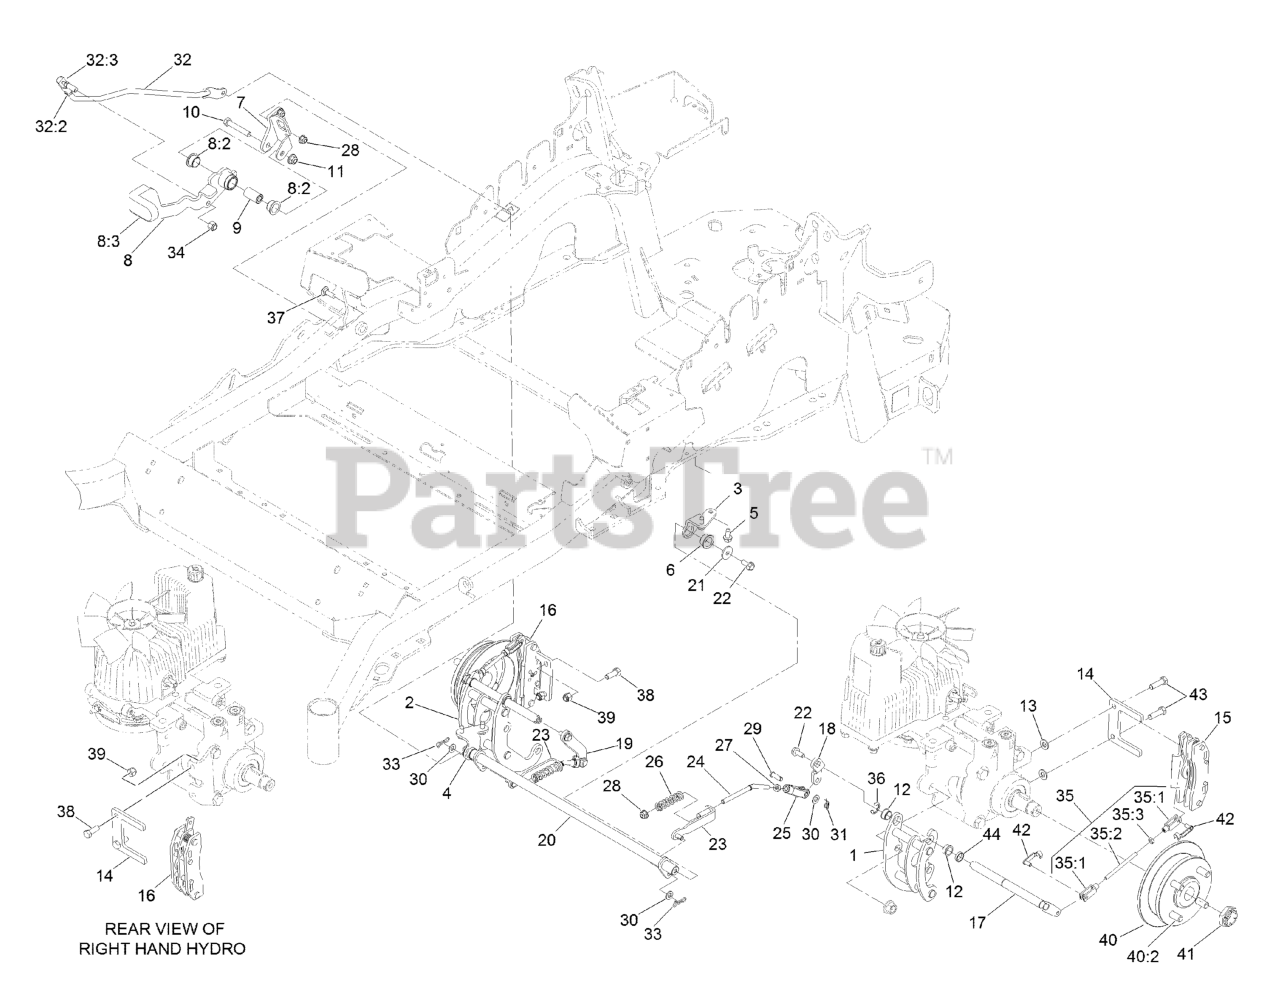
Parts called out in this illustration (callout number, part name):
1	BRACKET-MOUNT
2	BRAKE LEVER ASM W/ GRIP
2:2	BUSHING-FLANGE
2:3	GRIP-LEVER
3	BOLT-CARR
4	NUT-HF, NI
5	HANDLE-PIVOT, BRAKE
6	SCREW-HH
7	NUT-HF, NI
8	WHEEL HUB ASM
8:2	STUD-WHEEL
9	ASM-WHEEL AND TIRE
9:1	ASM-RIM 60
9:2	TIRE-DRIVE
9:3	Stem-Valve
10	CALIPER-BRAKE
11	CALIPER-BRAKE, RH
12	NUT-LUG
13	PLATE-MOUNT, BRAKE
14	SCREW-LOCK, PATCH
15	MOUNT-BELLCRANK, LH
16	MOUNT-BELLCRANK, RH
17	DECAL-TORQUE, WHEEL HUB LUG
18	BELLCRANK
19	BUSHING
20	ARM-INNER, LH
21	ARM-INNER, RH
22	LOCKNUT
23	WASHER-FLAT
24	MOUNT-PIVOT, LH
25	MOUNT-PIVOT, RH
26	Screw-HWH 5/16-18 X 3/4 Tf
27	BUSHING-FLANGE
28	SHAFT-CROSS
29	WASHER-FLAT
30	SCREW-HHF
31	BRACKET-L
32	LINKAGE-MID
33	YOKE-OFFSET
34	SPRING-COMPRESSION
35	NUT-JAM
36	PIN-CLEVIS
37	WASHER-PLAIN
38	PIN-COTTER, LOCKING
39	FRONT LINKAGE ASM
39:2	END-TIE ROD, RH
39:3	NUT-HJ
40	PIN-COTTER, LOCKING
41	NUT-LOCK
42	REAR LINKAGE ASM
42:3	NUT-JAM
44	SCREW-HH
45	NUT-LOCK, NI
47	PIN-CLEVIS, SPRING
